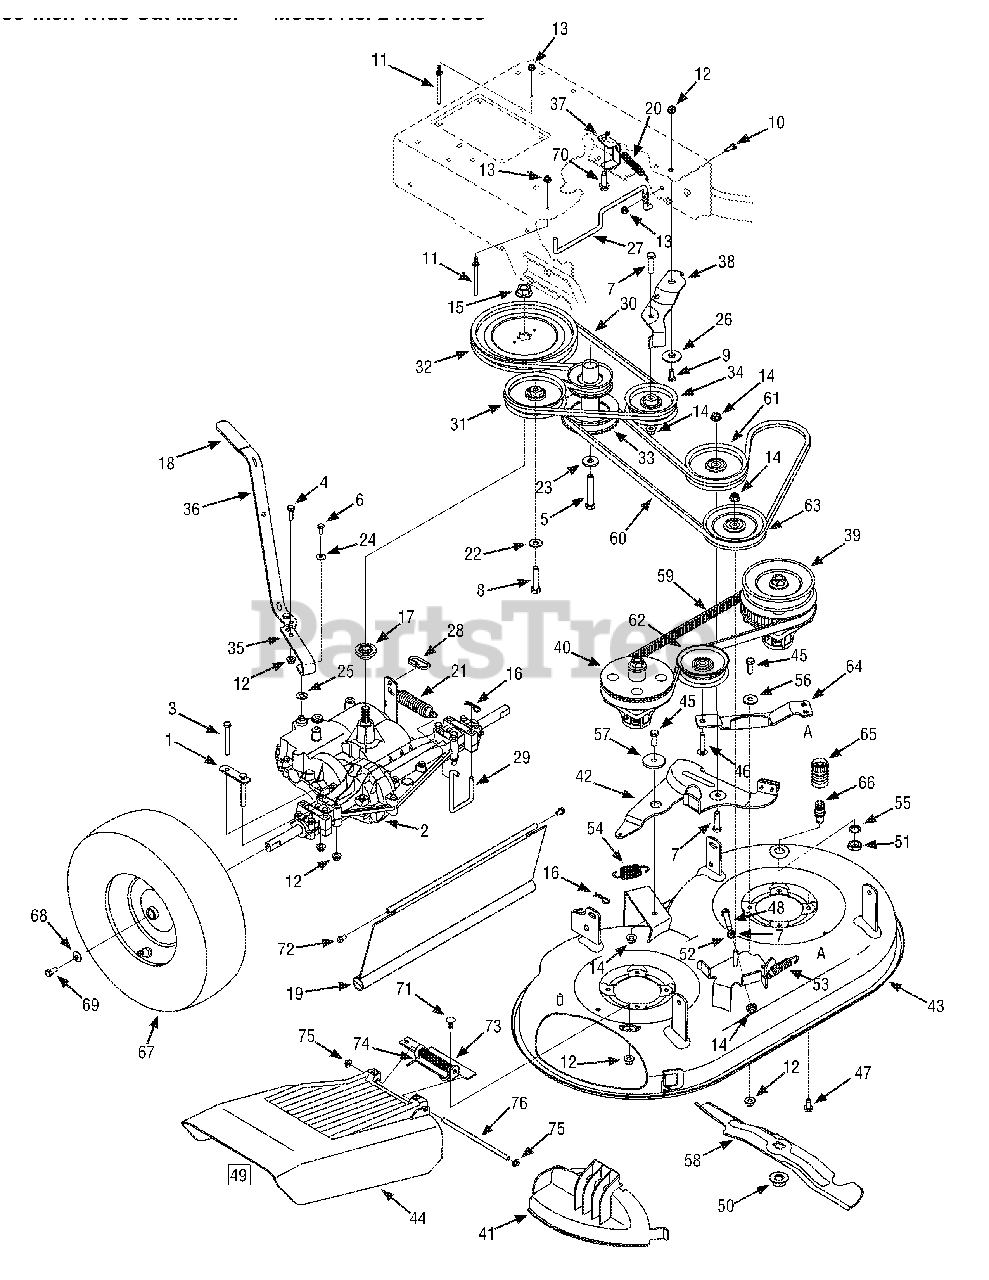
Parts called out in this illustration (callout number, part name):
1	Transaxle Bracket Mount
2	Transmission 4-Speed
3	Screw, HH Cap: 5/16-18 x 2.75"
4	Screw, HH Cap: 5/16-18 x 1.00"
5	Screw, HH Cap: 7/16-20 x 2.75"
6	Screw, HH Cap: 1/4-28 x .625"
7	Screw, HH Cap: 3/8-16 x 1.50"
8	Screw, HH Cap: 3/8-16 x 1.75"
9	Screw, HH Cap: 5/16-18 x .75"
10	Screw, HH Cap: 1/4-20 x .75"
11	Belt Keeper
12	Nut, Flange Lock: 5/16-18
13	Nut, Flange Lock: 1/4-20
14	Nut, Flange Lock: 3/8-16
15	Nut, Flange: 9/16-18
16	Hairpin Clip: 092" x 1.64" Long
17	Pulley Hub
19	Trailing Shield
20	Extension Spring
21	Extension Spring
22	Washer, Spring: .401" x .870" x .063"
23	Washer, Flat: 450" x 1.250" x .164"
24	Washer, Bell
25	Washer, Flat: .39" x .87" x .06"
26	Spacer, Shoulder: .50" x .1475"
27	Belt Keeper Rod
28	Loop Link Coupling
29	Trans Mount Rod
30	Belt, V Type, Drive Belt
31	Idler Pulley: 4.25" Dia.
32	Flat Sheave 7.75"
33	Engine Pulley 3.20" x 4.35" Dia.
34	Idler Pulley 3.50" Dia.
35	Shift Rod, Lower
36	Shift Rod, Upper
37	Belt Keeper
38	Wheel Drive idler Bracket
39	Drive Spindle Assembly
40	Spacer Spindle Assembly
41	Mulch Plug
42	Idler Arm Assembly
43	Deck Assembly 33-inch
44	Chute Deflector, 33" SD Deck
45	Screw, HH Cap: 3/8-16 x 1.00"
46	Screw, Carriage: 3/8-16 x 1.75"
47	Screw, 5/16-18 x .750
48	Screw, HH Cap: 3/8-16 x 2.00"
49	Chute Deflector Assy (includes ref. 73-77)
50	Nut, Flange: 5/8-18
51	Nut, Hex
52	Nut, Hex 3/8-16
53	Extension Spring: Timing Belt Tension
54	Extension Spring: Deck Brake
55	Washer, Lock
56	Spacer, Shoulder: .625" x .169"
57	Spacer, Shoulder: .884" x .190"
58	Blade: 17.9"
59	Belt, Timing
60	Belt, V Type, Deck Engagement Belt
61	Idler Pulley 4.25"
62	Idler Pulley 3.50"
63	Idler Pulley V-Type 5.0"
64	Idler Timing Bracket
65	Water Nozzle Adapter
66	Water Nozzle
67	Wheel 16 x 4 x 8
68	Washer, Bell: .340" x .872" x .060"
69	Screw, HH Cap: 5/16-24 x .75"
70	Screw, TT: 3/8-16 x 1.25"
71	Bolt, Carriage: 5/16-18 x .75"
72	Screw, HL: 1/4-15 x .50"
73	Deflector Hinge Bracket
74	Deflector Torsion Spring
75	Push Cap
76	Deflector Pin
